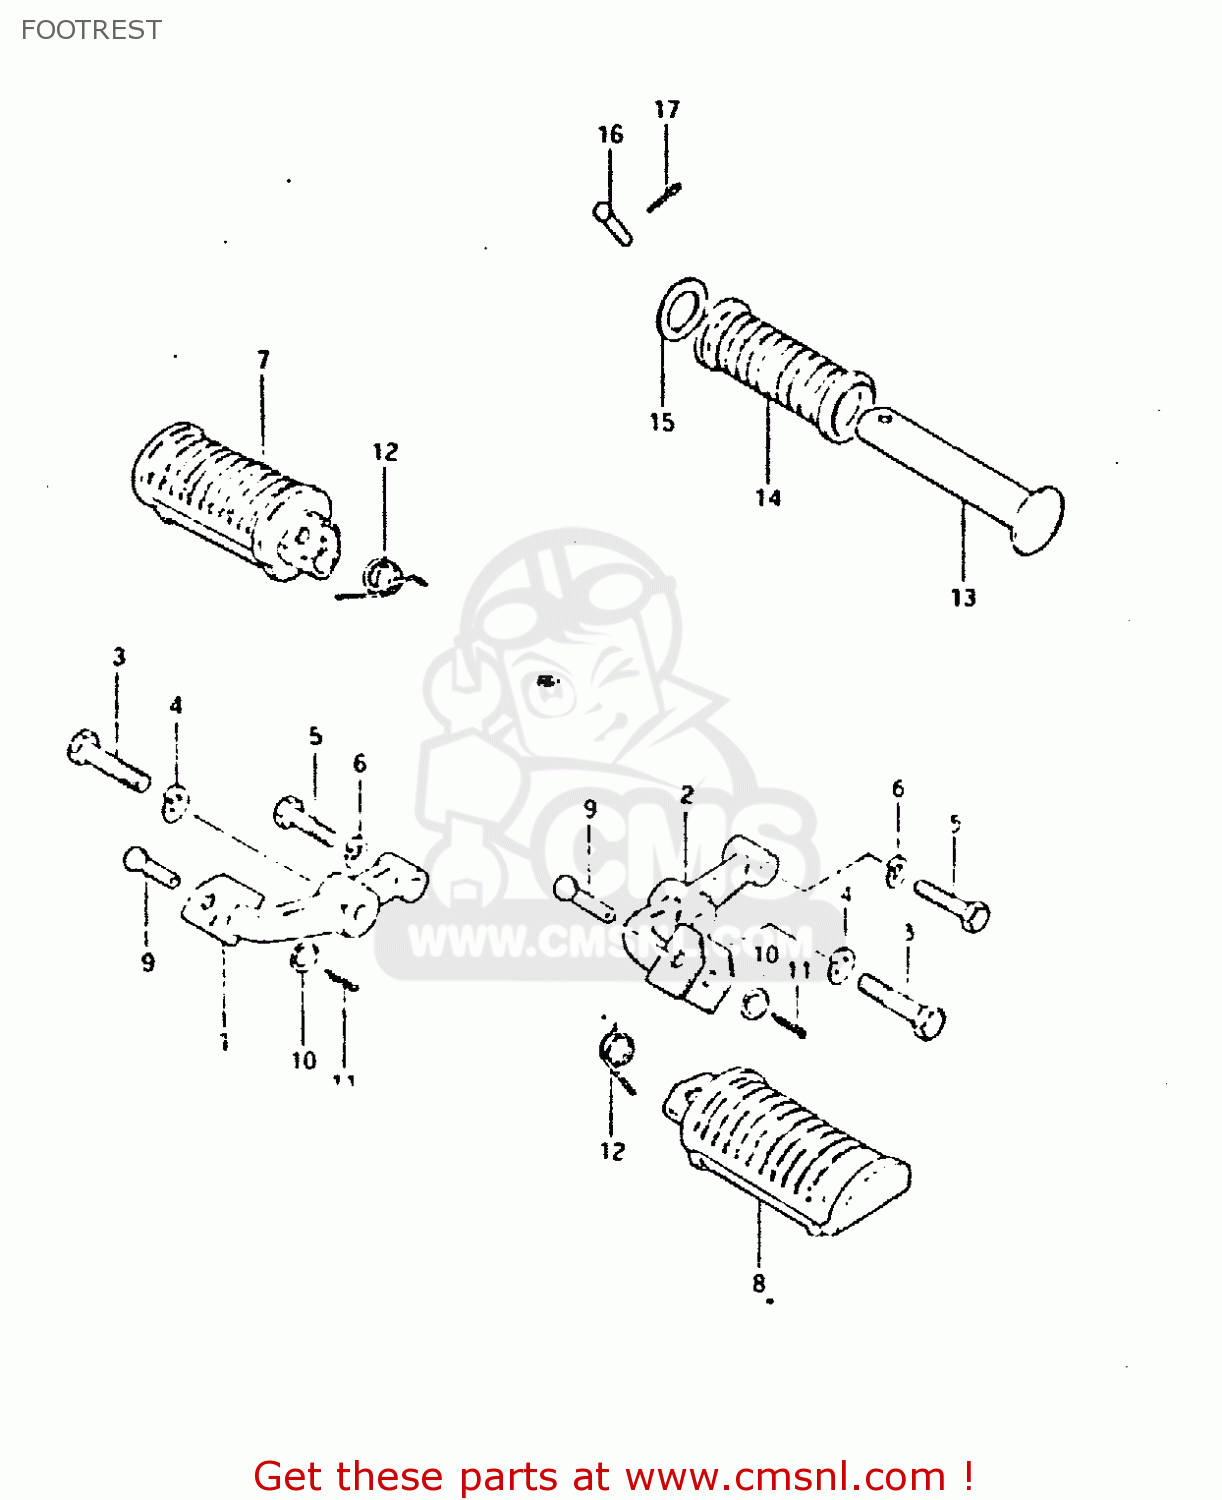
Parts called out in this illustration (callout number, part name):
1	BAR,FRONT FOOTREST,RIGHT
2	BAR,FRONT FOOTREST,LEFT
3	BOLT
4	LOCK WASHER
5	BOLT 8X40
6	LOCK WASHER
7	RUBBER,FRONT FOOTREST
8	FOOTREST
9	PIN
10	WASHER
11	PIN
12	SPRING
13	BAR,PILLION FOOTREST
14	RUBBER,PILLION FOOTREST
15	WASHER (19.5X32X2)
16	PIN
17	PIN
